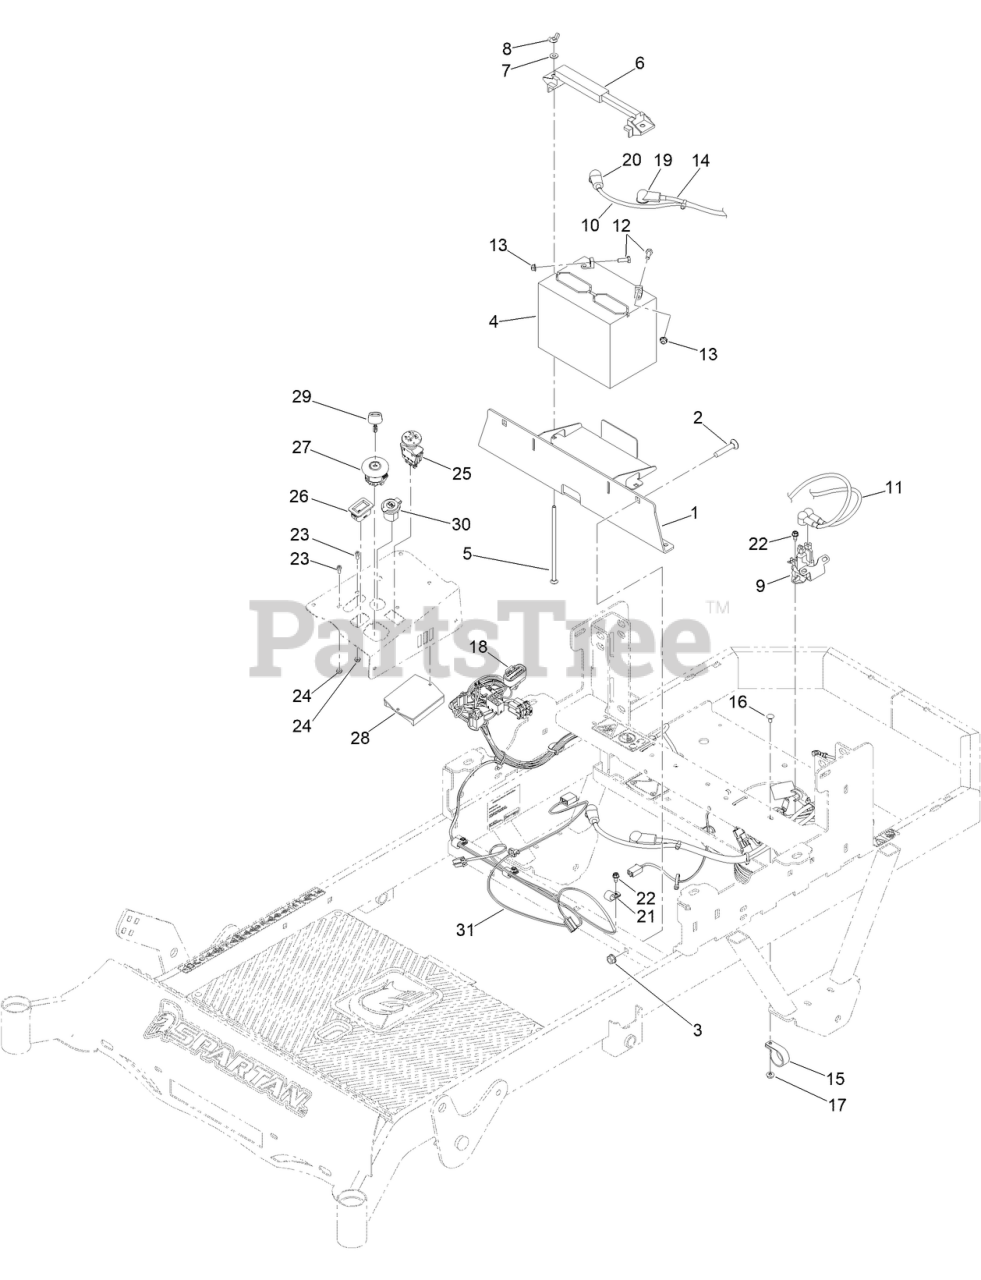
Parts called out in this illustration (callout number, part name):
1	MWR TTQ BATTERY BOX ASSY PAINT
2	SCREW-CARR
3	NUT-HHF, WHIZ
4	12 VOLT START BATTERY 300CCA
5	1/4-20 X 7 CARRIAGE BOLT ZINC
6	BATTERY HOLD DOWN
7	WASHER-FLAT
8	NUT-WING
9	HEAVY DUTY START SOLENOID
10	MWR NEGATIVE CABLE 28
11	MWR START WIRE 12
12	SCREW-HH
13	NUT-HF
14	MWR POSITIVE BATTERY CABLE 25IN
15	1-1/4IN CUSHIONED LOOP CLAMP BLACK
16	SCREW-CARR
17	1/4-20 HEX FLANGE NUT
18	MWR KEYSWITCH JUMPER HARNESS
19	3.15 LGTH STRAIGHT INSUL TERM COVER RED
20	STRAIGHT INSULATING TERMINAL COVER
21	CLAMP-R
22	SCREW-HWH
23	10-24 X 1/2 SOCKET C/S 18-8 SS
24	NUT-LOCK
25	PTO SWITCH
26	HOUR METER
27	IGNITION SWITCH
28	INTERLOCK MODULE
29	2023 MWR KEY
30	12 VOLT AUXILLIARY PLUG
31	RZ/RZ-PRO WIRING HARNESS
